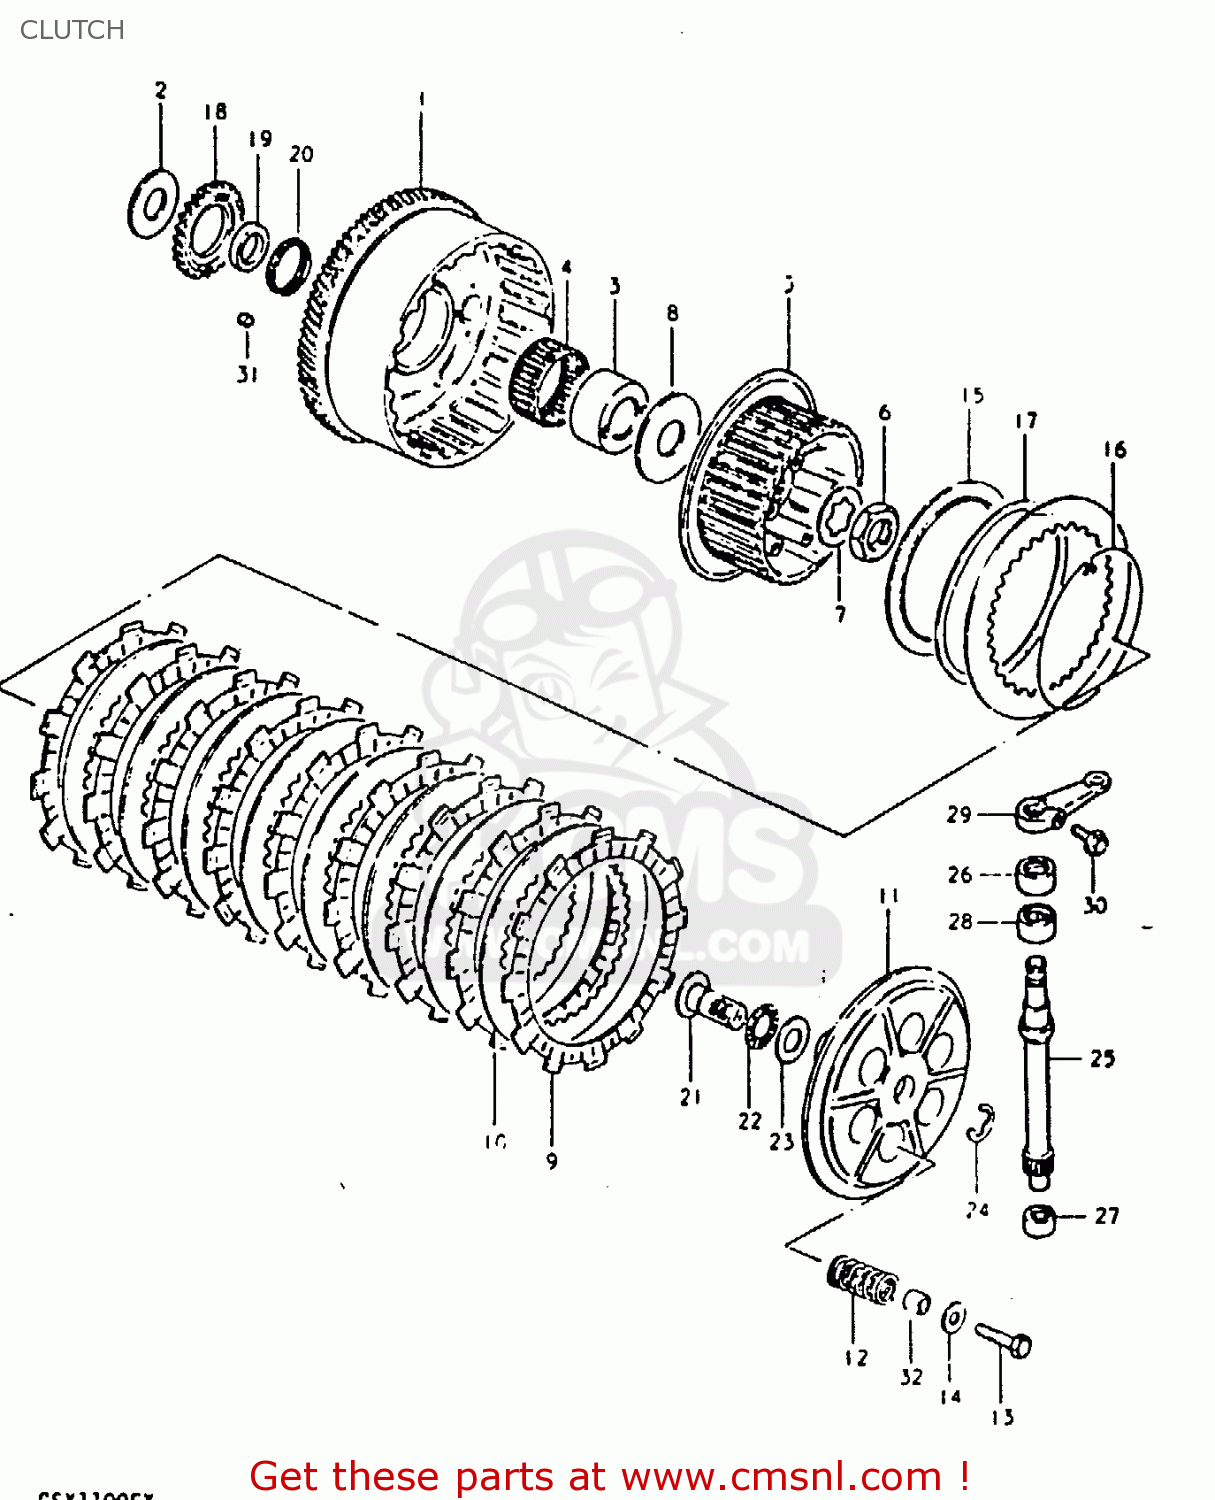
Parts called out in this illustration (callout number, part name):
1	GEAR ASSEMBLY,PRIMARY DRIVE
2	WASHER
3	SPACER
4	BEARING
5	HUB,CLUTCH SLEEVE
6	NUT
7	WASHER,LOCK
8	WASHER(25X66X3.5)
9	PLATE,CLUTCH DRIVE (MCA)
10	PLATE,CLUTCH DRIVEN (NAS)
11	DISC,CLUTCH PRESSURE
12	SPRING
13	BOLT
14	WASHER
15	SEAT,WAVE WASHER
16	RING,STOPPER
17	WASHER
18	GEAR,OIL PUMP DRIVE
19	SPACER,OIL PUMP DRIVE GEAR
20	BEARING(36X40X10)
21	RACK,CLUTCH RELEASE
22	BEARING(15X28X2)
23	WASHER
24	E RING 12MM
25	PINION,CLUTCH RELEASE
26	OIL SEAL
27	BEARING(12X19X12)
28	BEARING(15X22X12)
29	ARM,CLUTCH RELEASE
30	BOLT,REAR
31	CUSHION,PRIMARY DRIVEN GEAR
32	SPACER
